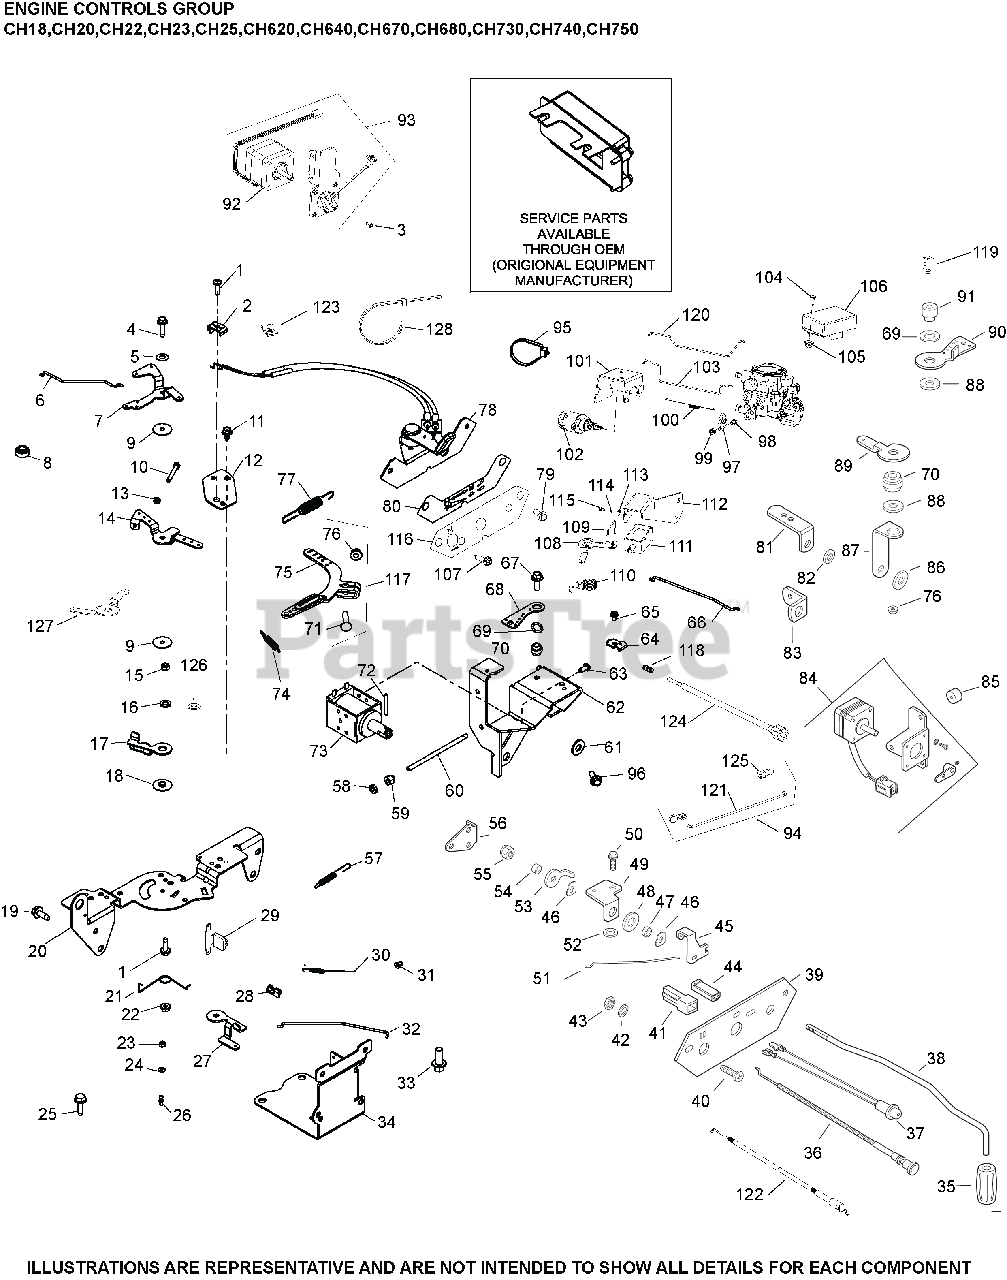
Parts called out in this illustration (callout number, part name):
1	SCREW, THREAD FORMING
2	CLAMP, CABLE
4	SCREW, THREAD FORMING - USE 25 086 473-S
5	WASHER, SPRING 1/4"
6	LINKAGE, CHOKE
7	LEVER, CHOKE
9	WASHER, FLAT 5.5 MM
10	SCREW, CAP M4X.7X30
13	NUT, M4X0.7
14	LEVER, THROTTLE CONTROL
15	NUT, FLG M5X.8
16	WASHER, SPRING LOCK 1/4"
20	BRACKET, CONTROL
21	SPRING, CHOKE RETURN
22	NUT, LOCK M5X.8
25	SCREW, THREAD FORMING
27	LEVER, THROTTLE ACTUATOR
28	BUSHING, THROTTLE LINKAGE
30	SPRING, LINKAGE
31	BUSHING, LINKAGE RETAINING
32	LINKAGE, THROTTLE
57	SPRING, THROTTLE LIMITER
71	BOLT, RD HD SQ NECK M6X1.0X25
75	LEVER, GOVERNOR - (#2409069S)
76	NUT, FLG M6X1.0
77	SPRING, GOVERNOR (RED)
117	LEVER, GOVERNOR ASSEMBLY
